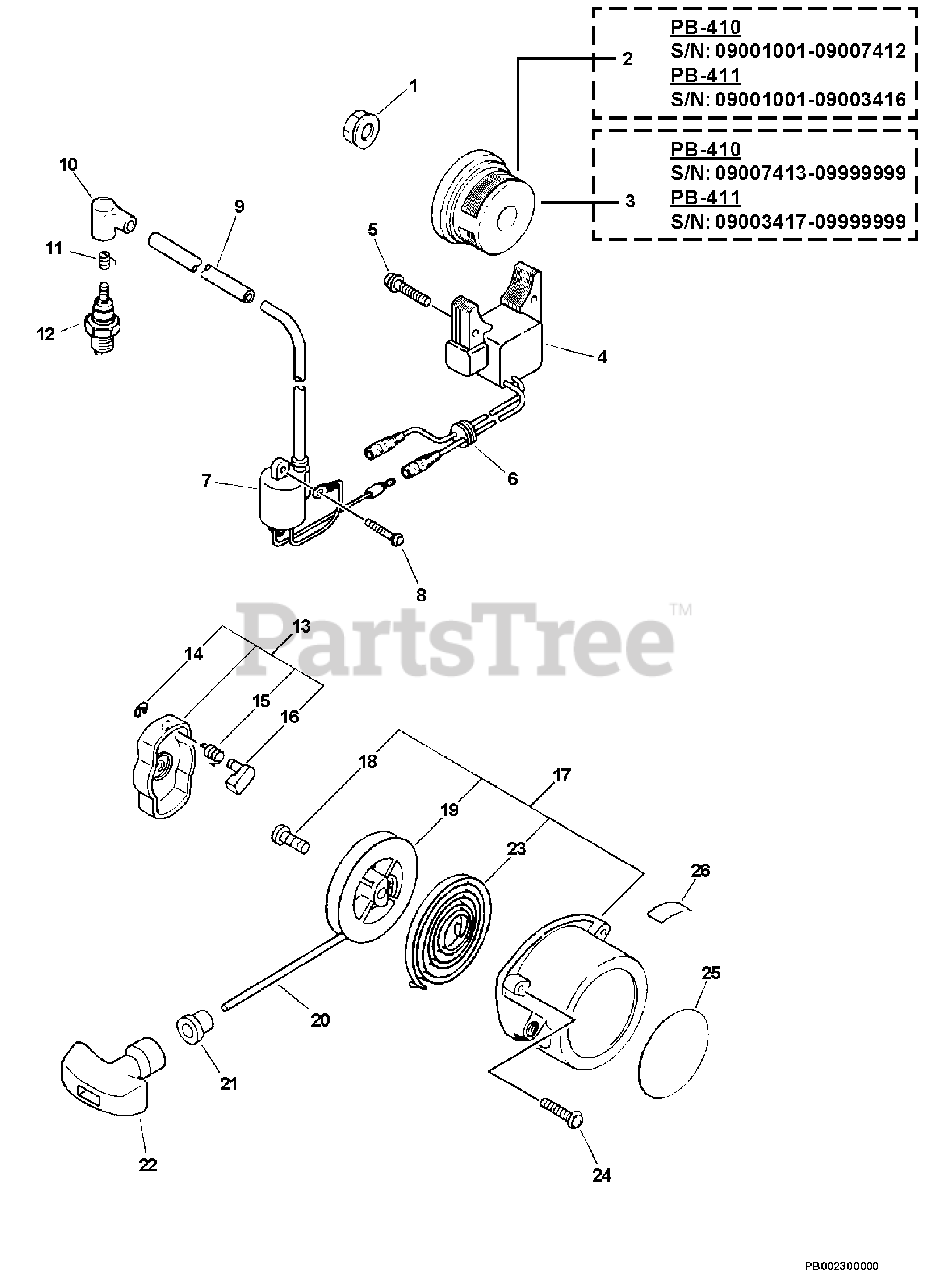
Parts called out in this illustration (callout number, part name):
1	NUT, FLANGE 10×1.25
2	FLYWHEEL
3	FLYWHEEL
4	COIL, IGNITION
5	SCREW 5×25
7	COIL, IGNITION
8	SCREW 4×16
9	TUBE, INSULATOR
10	CAP, SPARK PLUG
11	TERMINAL, SPARK PLUG
12	SPARK PLUG - BPM8Y
13	PAWL CATCHER ASSY
14	E-RING 4
15	SPRING, RETURN
16	PAWL, STARTER
17	STARTER ASSY
18	SCREW
19	REEL, ROPE
20	ROPE, STARTER 4.0×880
21	GUIDE, ROPE
22	GRIP, STARTER
23	SPRING, RECOIL
24	SCREW 5×18
25	LABEL, ECHO
26	LABEL, CAUTION - HOT
